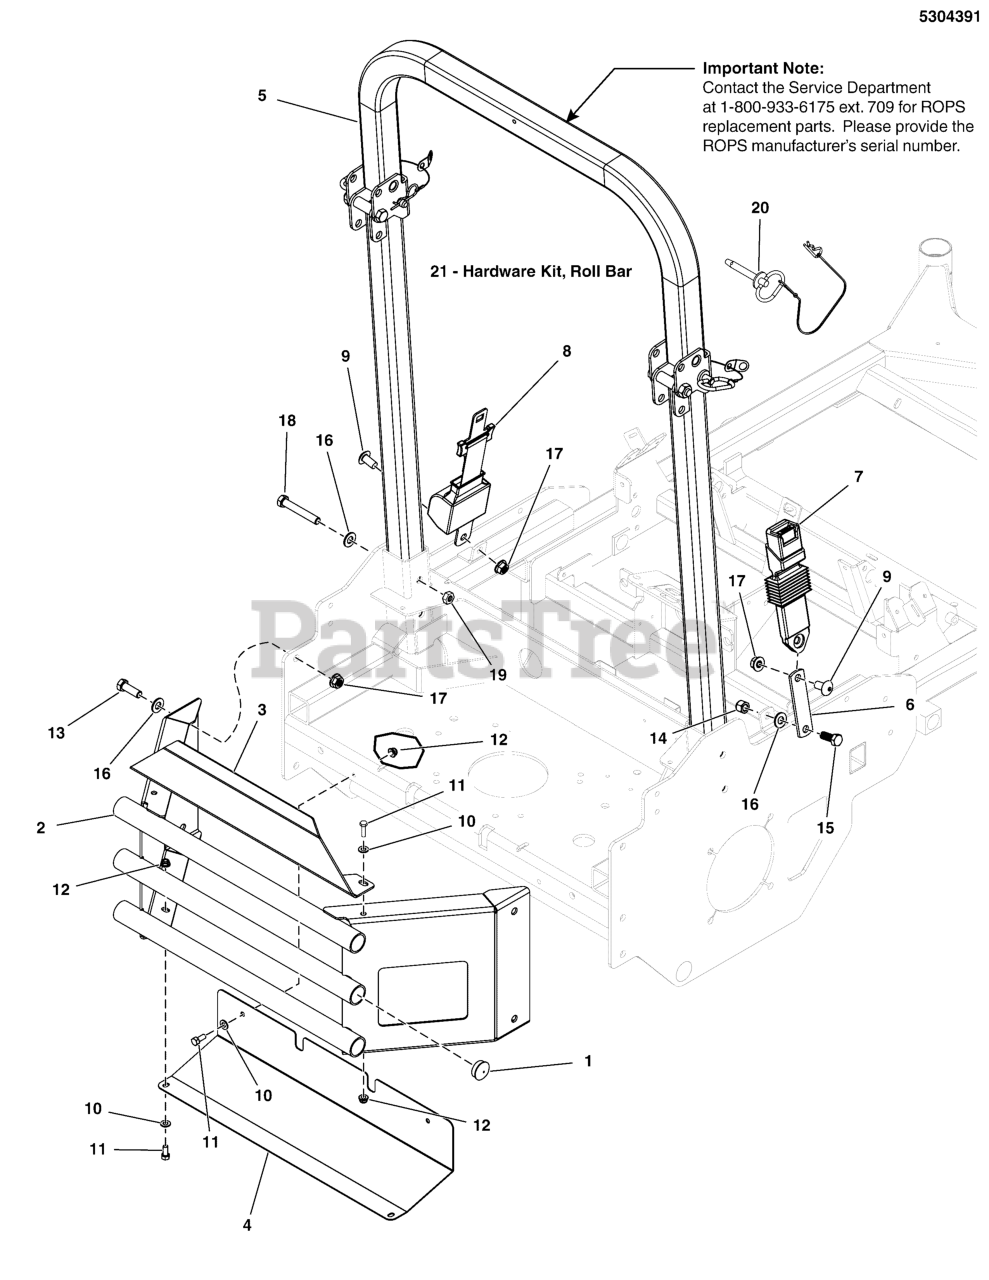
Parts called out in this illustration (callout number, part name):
1	PLUG, PANEL, 1.25 - BLACK
2	WELD, BUMPER - F210Z - RED
3	PLATE, CARB PROTECTOR, F210Z - RED
4	PLATE, HEAT SHIELD - BLK
5	ROPS (Call 1-800-933-6175 ext. 2193 if replacing a ROPS)
6	EXTENSION, SEAT BELT - BLK
7	SEAT BELT ASSM, RETRACTOR + SUP SLEEVE
8	ORDER P/N 5105137 (CONTAINS BOTH SEAT BELT RETRACTOR & SUPER SLEEVE BUCKLE)
9	SCREW, 1/2-13 X 1.00, SHCS
10	WASHER, 5/16" SAE
11	BOLT, 5/16-18 X 3/4 GD5
12	NUT, 5/16-18 HEX NYLOCK FLANGE
13	BOLT, 1/2-13 X 1-1/2 GD5 CZ
14	NUT, 1/2-13 HEX NYLON LOCK
15	BOLT, 1/2-13 X 1-1/4 GD5 CZ
16	WASHER, 1/2 SAE
17	NUT, Hex Flange, Nylock, 1/2-13
18	BOLT, 1/2-13 X 3-1/4, HEX HD, GD5, CZ (SV)
19	NUT, 1/2-13 HEX SIDE LOCK
20	PIN, HITCH, .50 X 3.25 W/ LAY
21	HARDWARE KIT, ROLL BAR
